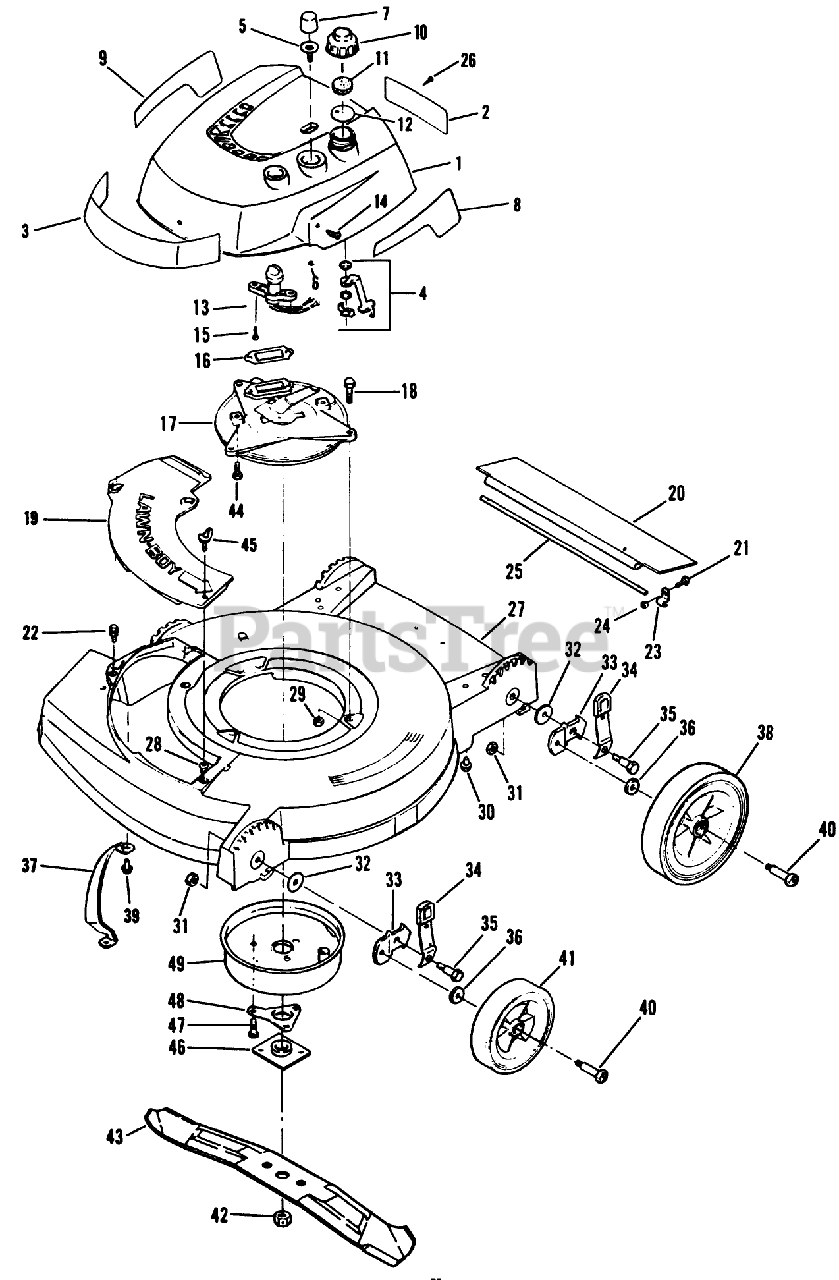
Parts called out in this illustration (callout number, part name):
6	LOCKNUT S
9	DECAL
11	BAFFLE - FOAM SM
12	GASKET S
13	SWITCH
14	SCREW-SEMS
18	SCREW
23	CLAMP ROD KMC
24	LOCKNUT E
25	ROD T/SHIELD ADV WIRE
25	ROD 21" ADVANCE
26	SCREW S
29	NUT-LOCK F
30	SCREW
31	LOCKNUT
32	WASHER
36	WASHER WROUGHT
37	TOE BAR 19"
37	BAR-TOE
42	NUT-BLADE
43	Blade-19"
44	SCREW V
45	WING SCREW LAWRE
46	PLATE AND COLLAR ASM
47	SCREW
48	SUPPORT F
49	MUFFLER COVER F
